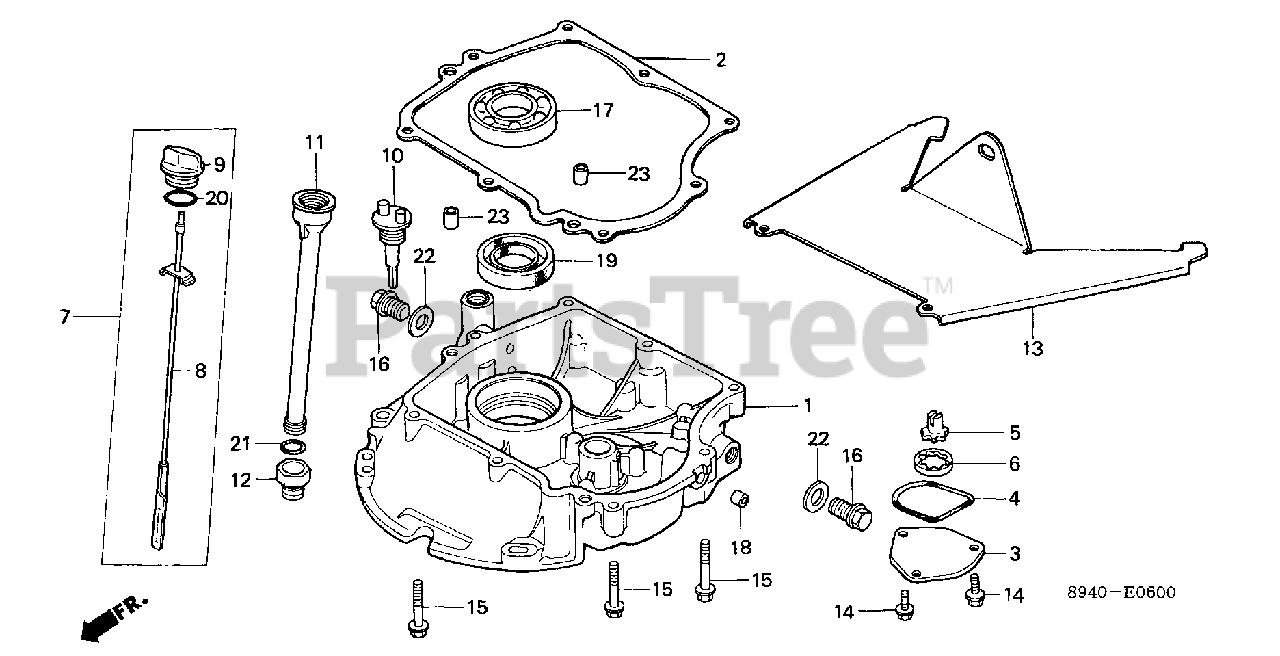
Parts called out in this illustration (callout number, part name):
2	GASKET, OIL PAN
3	COVER, OIL PUMP
4	O-RING, COVER
5	ROTOR (INNER)
6	ROTOR, OIL PUMP (OUTER)
7	GAUGE ASSY., LEVEL
7	GAUGE ASSY., OIL LEVEL
8	DIPSTICK, OIL
10	CAP, OIL FILLER
11	PIPE, OIL FILLER
12	BOLT, JOINT
14	BOLT, FLANGE (6X12) (CT200)
15	BOLT, FLANGE (6X32)
16	BOLT, DRAIN PLUG (12X15)
16	BOLT, DRAIN PLUG
17	BEARING, RADIAL BALL
18	OIL SEAL (6X11X4)
19	OIL SEAL (25.4X40X7)
20	O-RING (26X2.7)
21	O-RING (15X2.5)
22	WASHER, DRAIN PLUG (12MM)
23	PIN A, DOWEL (8X14) (YAMADA)
